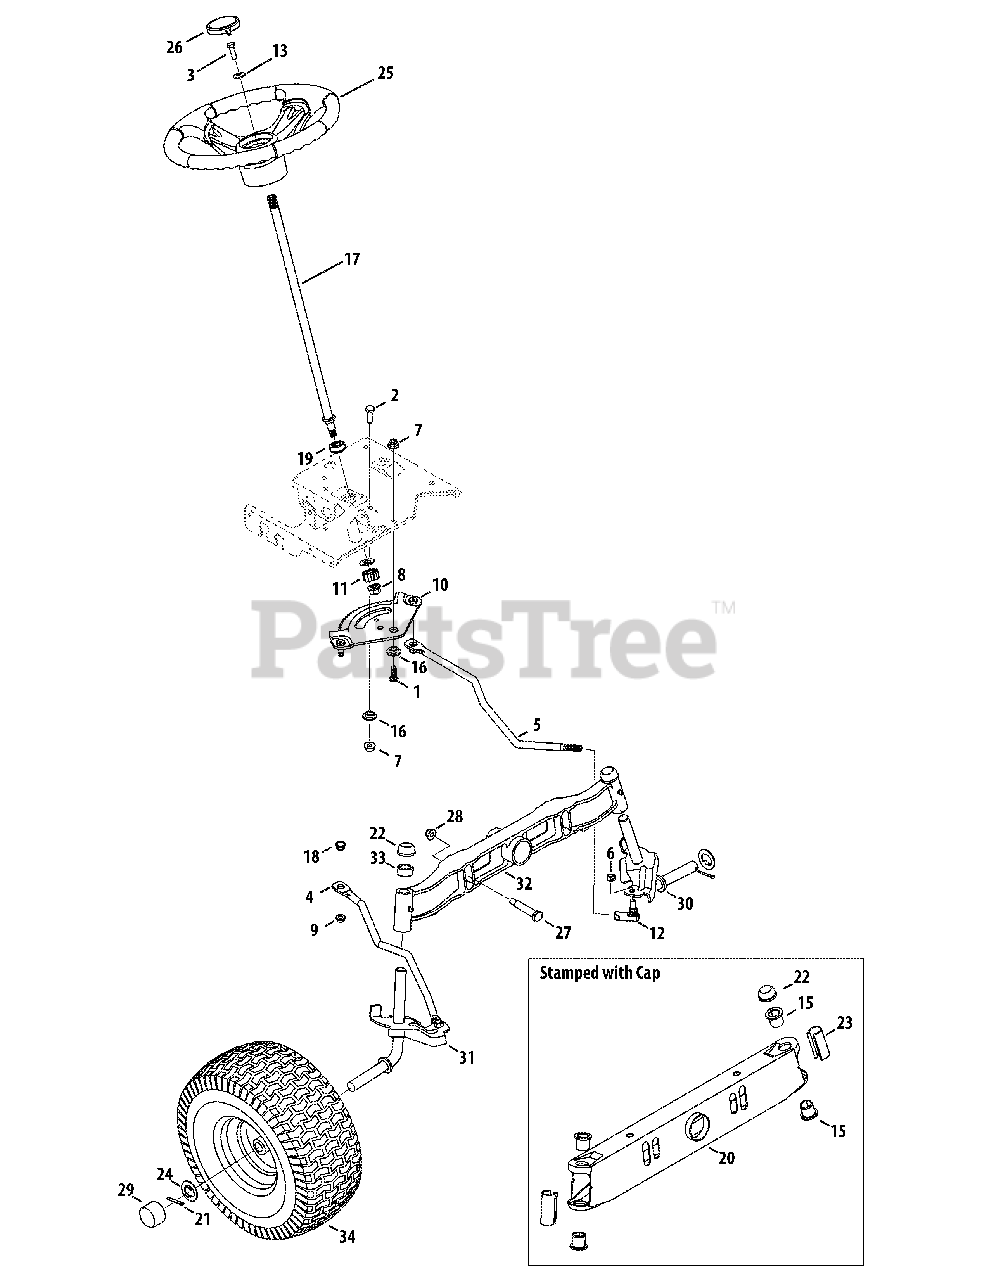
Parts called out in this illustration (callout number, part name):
1	Hex Screw, 3/8-16, 1.00, Gr5
2	Hex Screw, 3/8-16, 1.00, Gr5
3	Hex Screw, 5/16-18, 1.00, Gr5
4	Link, Drag, RH
5	Link, Drag, LH
6	Nut, Hex Lock, 3/8-24
7	Nut, Flange Lock, 3/8-16, Grf
8	Nut, Flange Lock, 7/16-20
9	Nut, Flange Lock, 5/16-18, Gr5
10	Gear, Steering, 11/90 Ratio
11	Gear, Pinion, Steering
12	Ball Joint, 7/16-20, Lock
13	Washer, Flat, .406 x .875 x .105
14	Washer, Flat, .51 x 1.12 x .06
15	Flange Bearing
16	Spacer, Shoulder, .38 x 1.00 x .31
17	Shaft, Steering, .625 OD x 24.25
18	Plastic Bushing .380 ID
19	Hex Flange Bearing
21	Cotter Pin, 5/32 x 1.25 (Cast Axle)
22	Push Cap, 3/4
23	Pivot Bar End Cap
24	Flat Washer, .781 x 1.59
25	Steering Wheel
26	Steering Wheel Cap, Sprig Logo
26	Steering Wheel Cap, TB Logo
27	Shoulder Bolt, .5 x 2.38, 3/8-16
28	Flange Lock Nut, 3/8-16
29	Hub Cap, Standard
30	LH Axle Assembly, .750
31	RH Axle Assembly, .750
32	Pivot Bar, Cast Iron
33	Spacer, Shoulder, .71 x .125 x .56
34	Wheel Assembly Complete, 15x6
